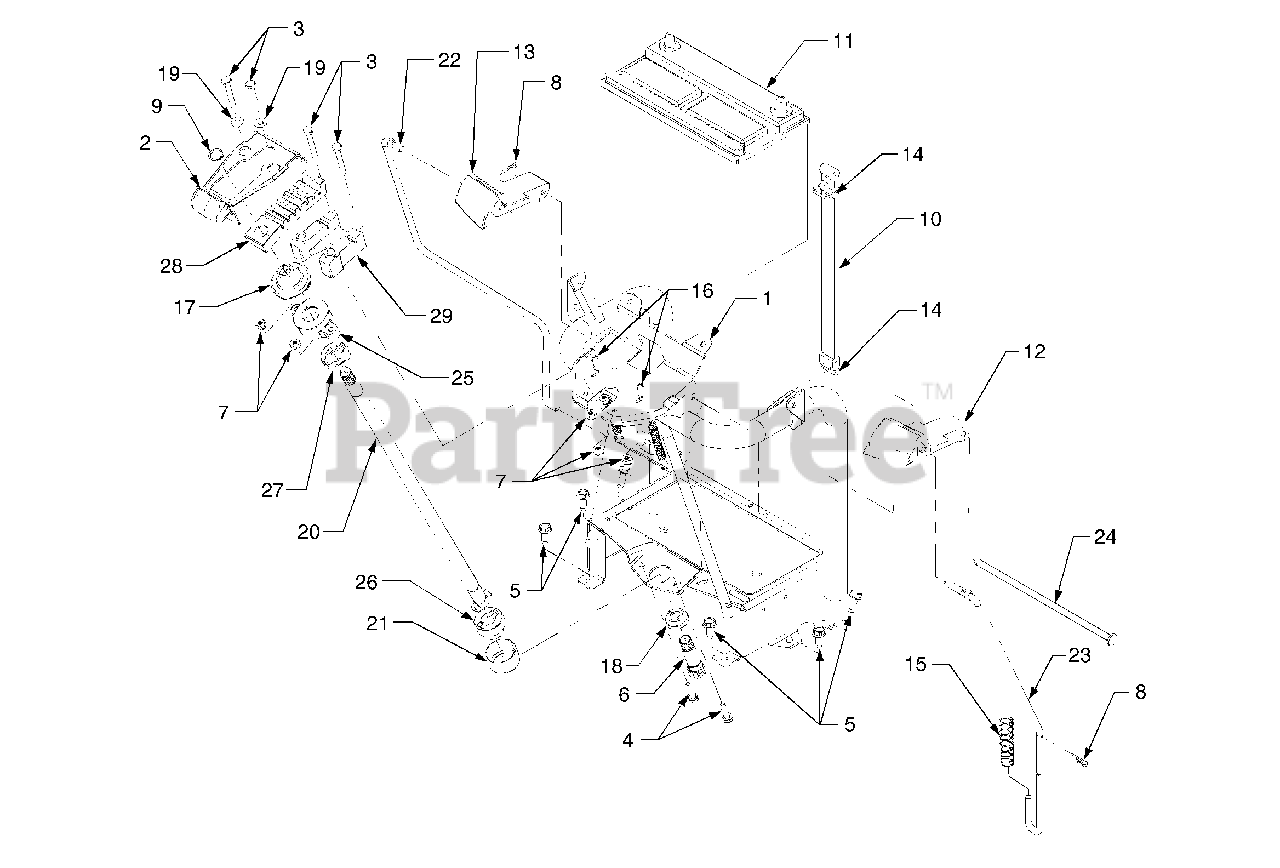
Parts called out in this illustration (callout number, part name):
1	Pedestal Assembly
2	Handle, Tilt
3	Screw, Hex Cap 1/4-20 x 1.75 GR5
4	Screw, Hex Cap 1/4-20 x 1.0 GR5
5	Screw, Hex Wash. Hd. Tapp 5/16-18 x .75
6	Shaft, Lower Steering
7	Nut, Hex Insert Lock, 1/4-20
8	Pin, Internal Cotter
9	Ring, Retaining, .56 Dia Shaft
10	Strap, Battery
11	Battery
12	Lever, Park Brake
13	Lever, Cruise
14	Hook, Wire Rectangular
15	Spring, Compression, .676 x 2.57
16	Spring, Extension
17	Boot, Tilt Wheel Coupling
18	Boot, Shaft Cover
19	Washer, Flat, .271 x .63 x .065
20	Shaft, Upper Steering
21	Bearing, Sleeve, 1.44 x 1.5 x .812
22	Rod, Cruise Control
23	Rod, Parking Brake
24	Rod, Cruise/Brake Pivot
25	Housing, Tilt Wheel Coupling
26	Coupling Half, Bottom
27	Coupling Half, Top
28	Index, Tilt Steering
29	Block, Tilt Steering
